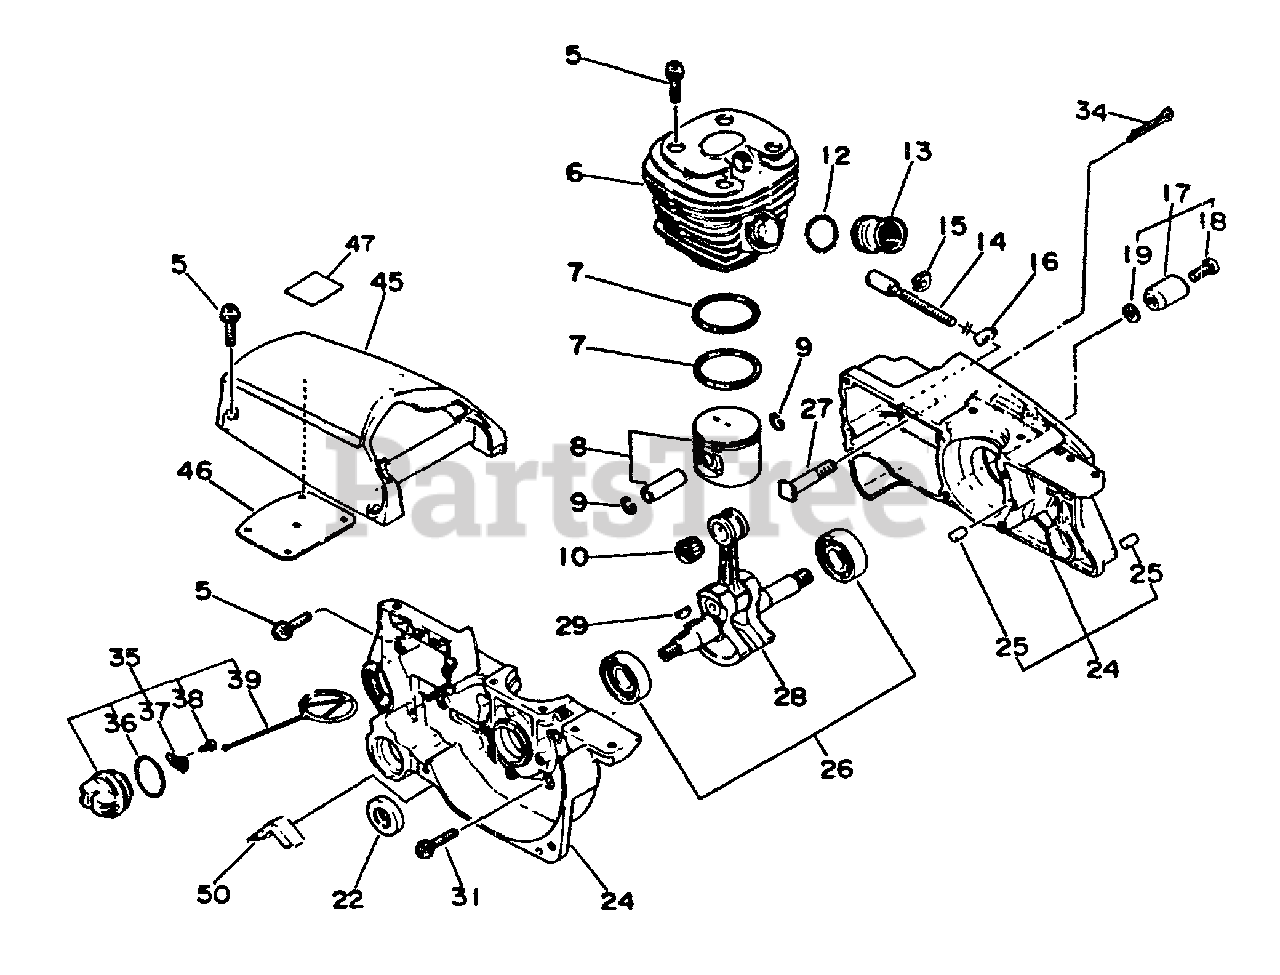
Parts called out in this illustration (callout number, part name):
5	SCREW - 5×20
6	CYLINDER
7	RING, PISTON
8	PISTON KIT
9	RING, SNAP 8
10	BEARING, NEEDLE
12	BAND
13	BELLOWS, INTAKE
14	SCREW, ADJUSTER
16	TENSIONER
17	CHAIN CATCHER KIT
18	SCREW - 5×20
19	WASHER, FLAT 5.5×10×0.8
22	SEAL, OIL
24	CRANKCASE KIT
25	PIN, LOCATING 5×10
26	BEARING SET
27	STUD, GUIDE BAR 8
28	CRANKSHAFT ASSY
29	KEY, WOODRUFF
31	SCREW - 5×30
34	PIN, COTTER
35	CAP ASSY
37	RETAINER, CONNECTOR
38	SCREW 3×8
39	CONNECTOR, CAP L= 60 MM
45	COVER, CYLINDER
47	LABEL - KICK BACK
50	CUSHION
